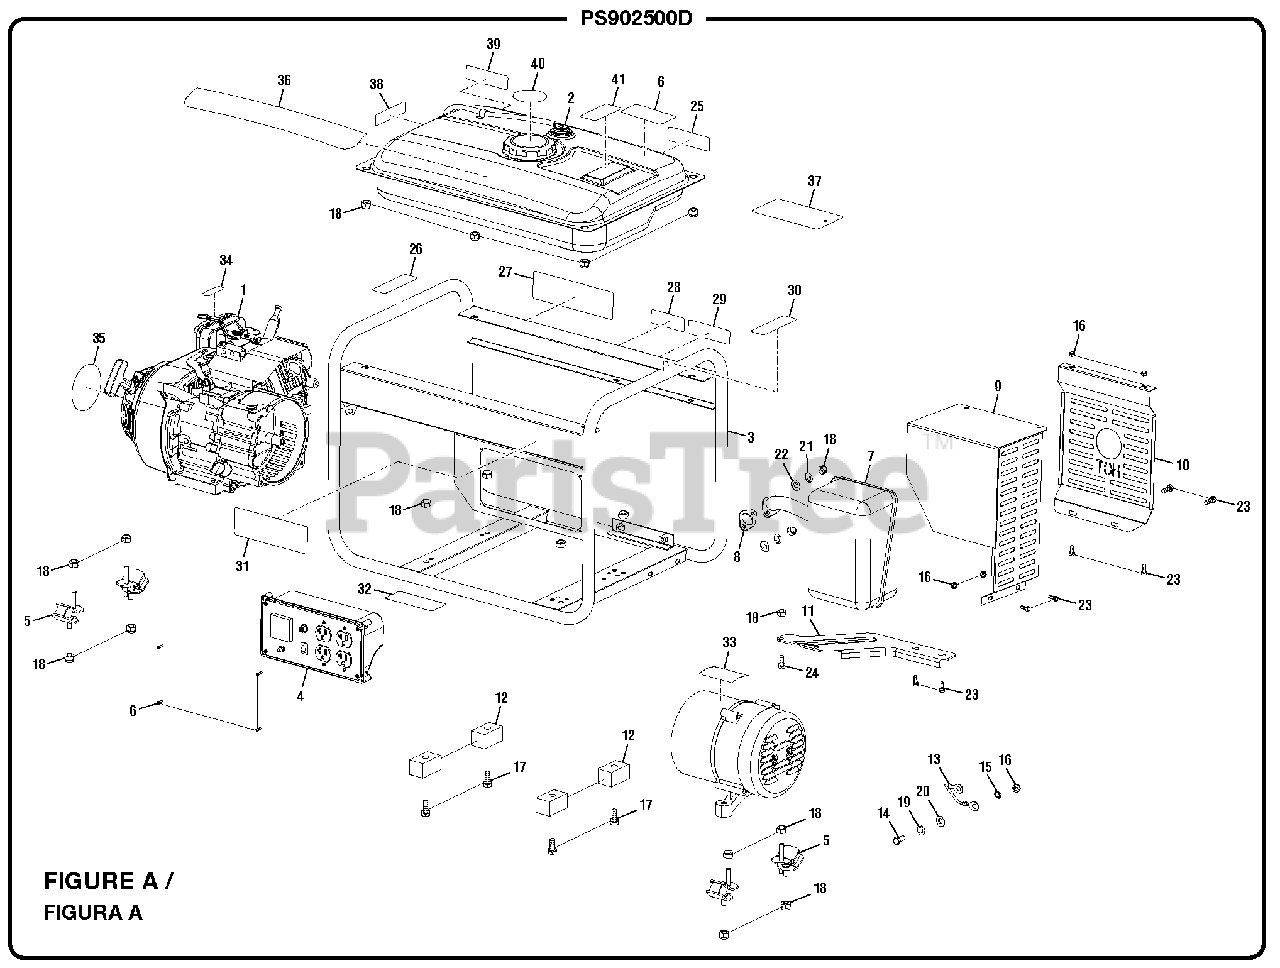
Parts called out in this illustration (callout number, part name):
2	Fuel Tank Assembly
3	Frame Assembly
4	Control Panel Assembly
6	CPSC Label
8	Muffler Gasket
9	Heat Shield (Outer)
10	Heat Shield
11	Muffler Support
13	Ground Wire Assembly
14	Bolt (M6 x 14 mm, Flange Hd.)
15	Lock Washer (M6)
16	Flange Nut (M8)
17	Bolt (M8 x 25 mm, Flange Hd.)
18	Flange Nut (M8)
19	Spring Washer (M6)
20	Washer (M6)
21	Spring Washer (M8)
22	Washer (M8)
23	Bolt (M6 x 12 mm, Flange Hd.)
24	Bolt (M8 x 35 mm, Flange Hd.)
25	Combustion Label
26	Fire Danger Label
27	Danger Label
28	Hot Surface Label
29	Fire Distance Label
30	Ground Warning Label
31	Rating Label
32	Check Oil Label
33	Data Label
34	Choke Label
35	Recoil Label
36	Logo Label
37	Warning Hang Tag
38	Start Label
39	Inquiries Label
40	Fuel Stabilizer Label
41	E85 Label
